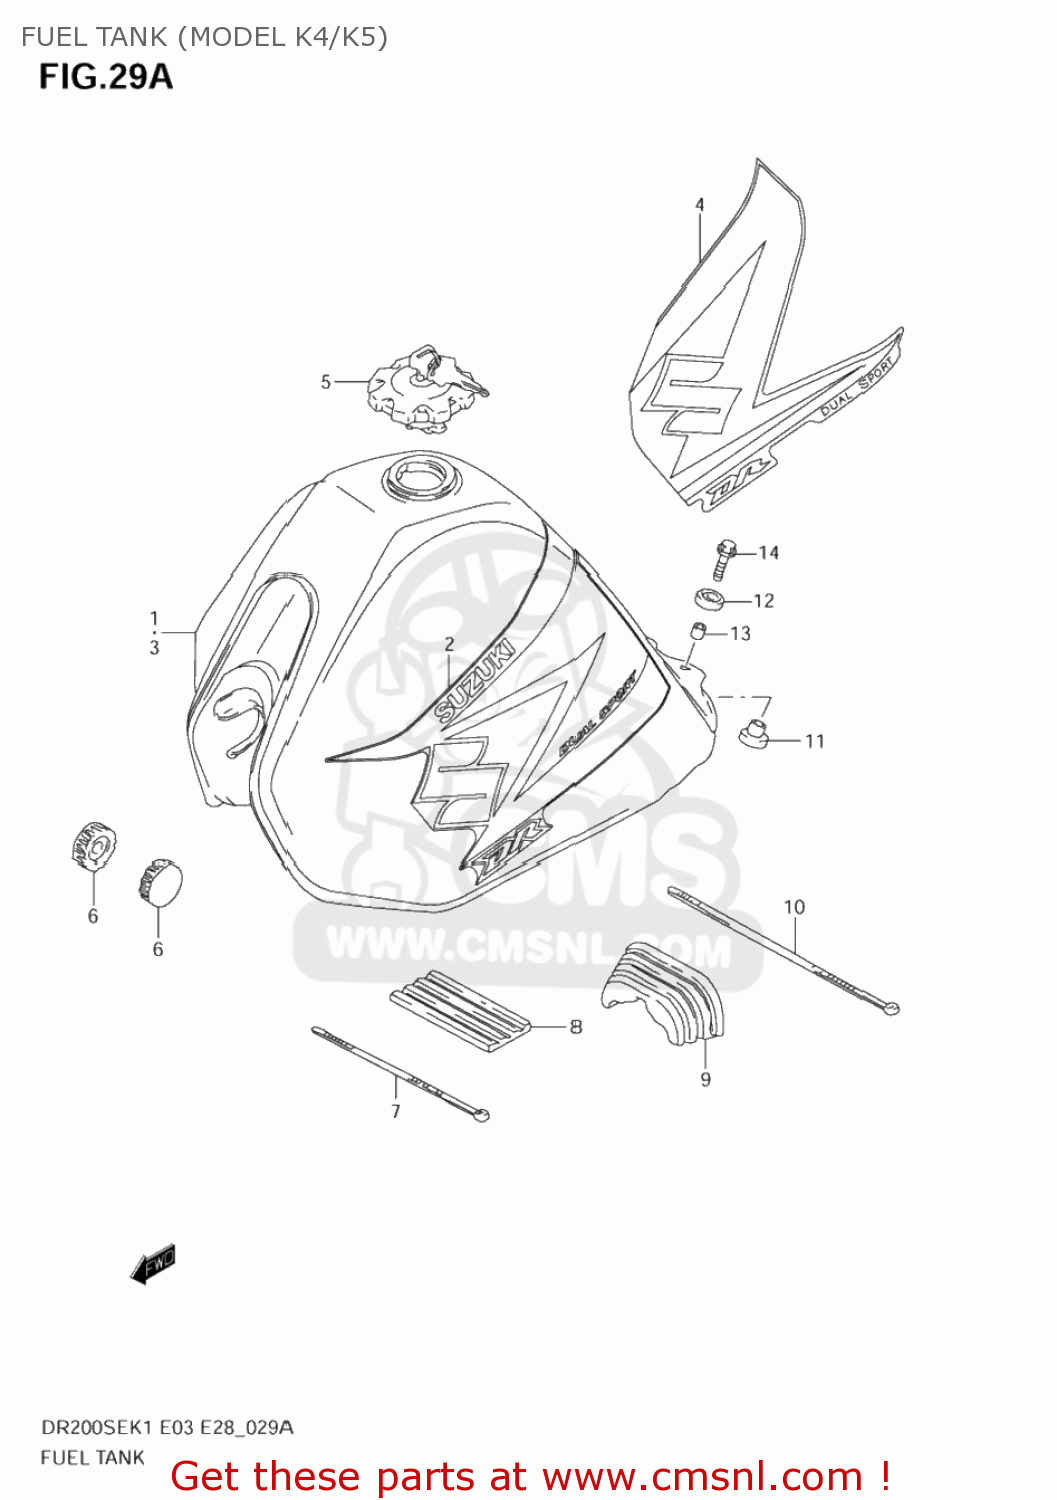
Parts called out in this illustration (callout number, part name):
1	TANK ASSY,FUEL(BLUE)
2	TAPE SET,FUEL TANK
3	TANK ASSY,FUEL(BLUE)
4	TAPE SET,FUEL TANK(BLUE)
5	CAP SET,FUEL TANK
6	CUSHION
7	CLAMP(L:250)
8	CUSHION,FUEL TANK UPR FR
9	CUSHION,FUEL TANK RR
10	CLAMP(L:300)
11	CUSHION
12	CUSHION
13	SPACER(6.5X9X18)
14	BOLT
